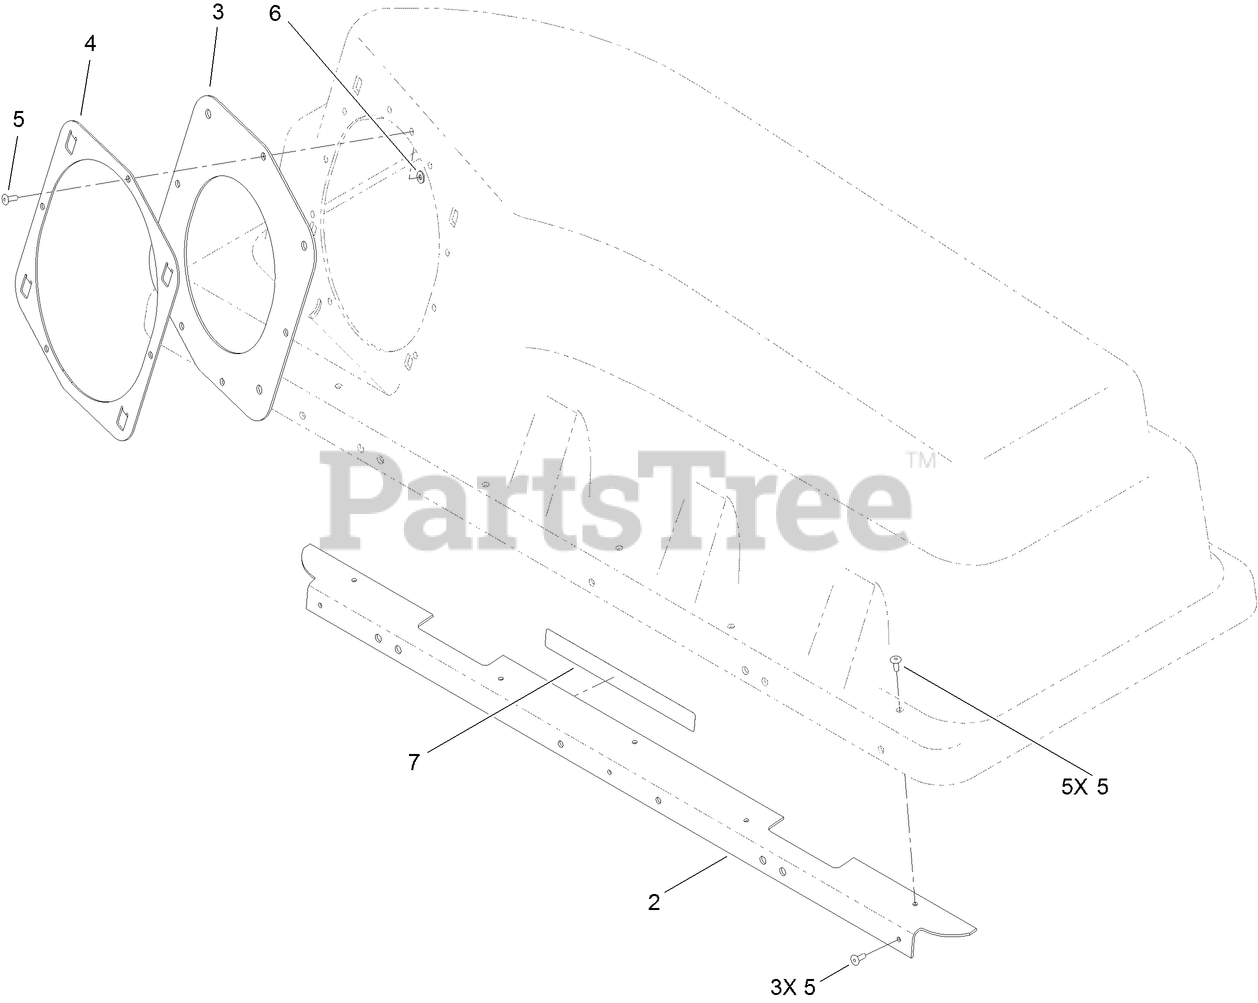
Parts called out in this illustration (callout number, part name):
2	STIFFENER-BAGGER TOP
3	GASKET
4	RING-RETAINER
5	RIVET-BLIND
6	WASHER-FLAT
7	DECAL-CAUTION, BAGGER
